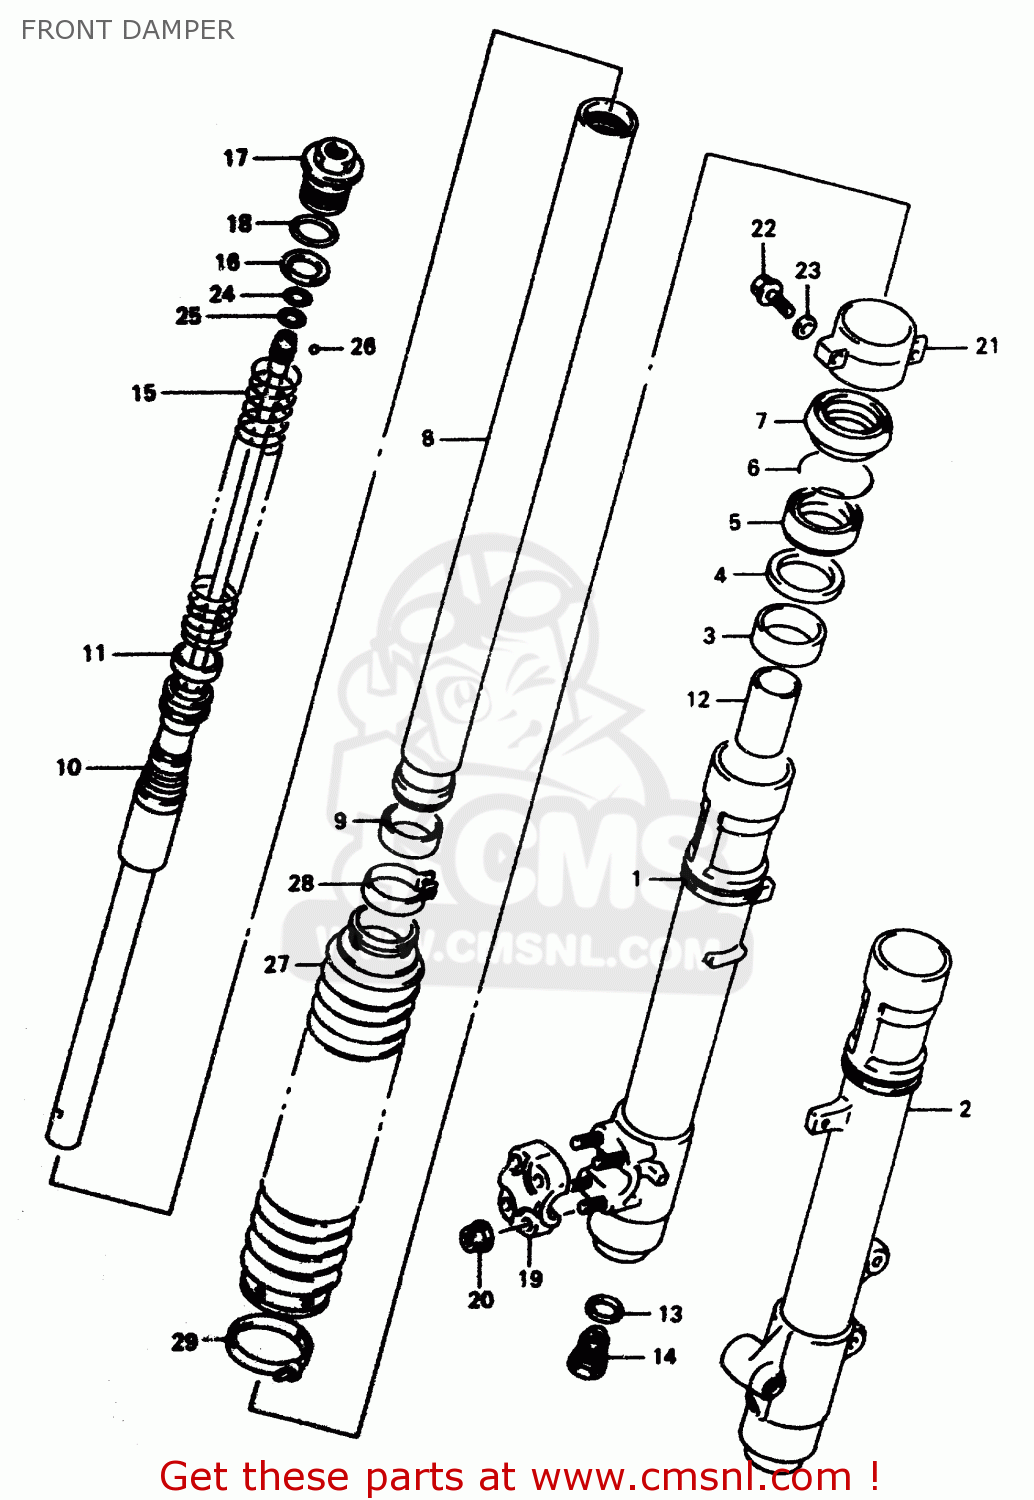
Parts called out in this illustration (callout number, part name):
1	TUBE,OUTER,RIGHT
2	TUBE,OUTER,LEFT
3	BUSH,GUIDE
4	SPACER,SEAL
5	SEAL,OIL
6	CIRCLIP,FORK OIL SEAL
7	DUST SEAL
8	TUBE,INNER
9	BUSH,SLIDE
10	ROD,FR DAMPER
11	BUSH,SLIDE
12	PIECE,OIL LOCK
13	GASKET (NAS)
14	BOLT,CTR
15	SPRING,FRONT
16	SEAT,SPRING LWR
17	BOLT,FORK
18	O RING
19	HOLDER,AXLE
20	NUT
21	HOLDER
22	BOLT
23	WASHER (5.3X10X1.0)
24	O-RING (D:2.4 ID:13.8)
25	EXPANDER
26	BALL
27	BOOT
28	BAND,BOOT UPR
29	BAND,BOOT LWR
